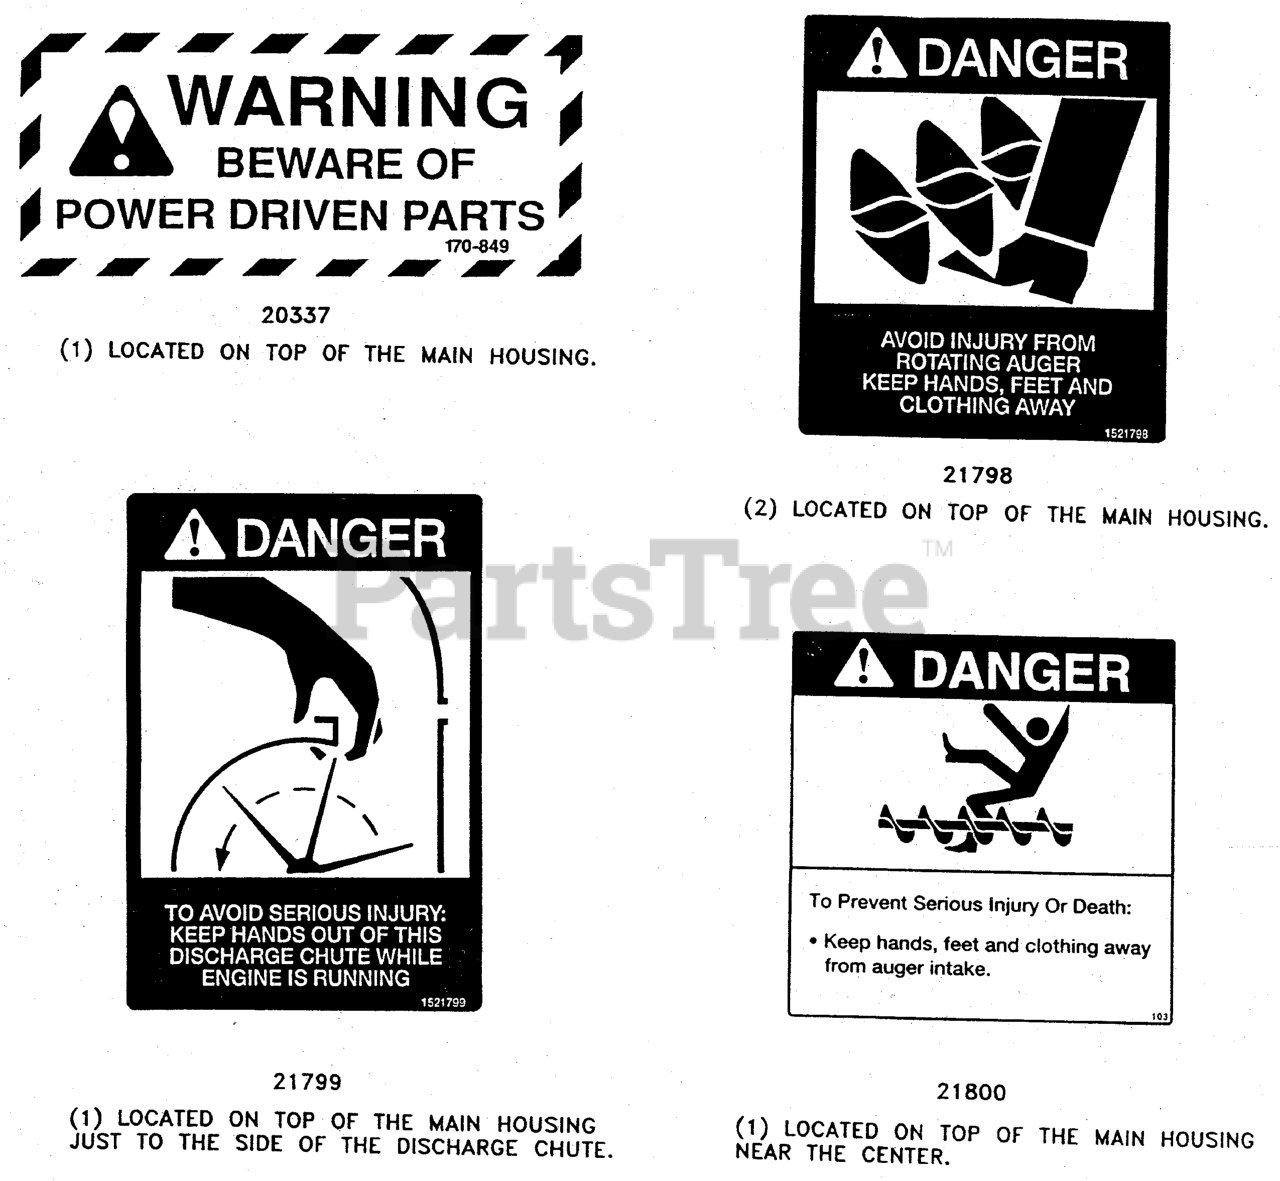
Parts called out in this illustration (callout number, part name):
1	DECAL, Warning
2	DECAL, Danger
3	DECAL, Danger, Discharge
4	DECAL, Danger
